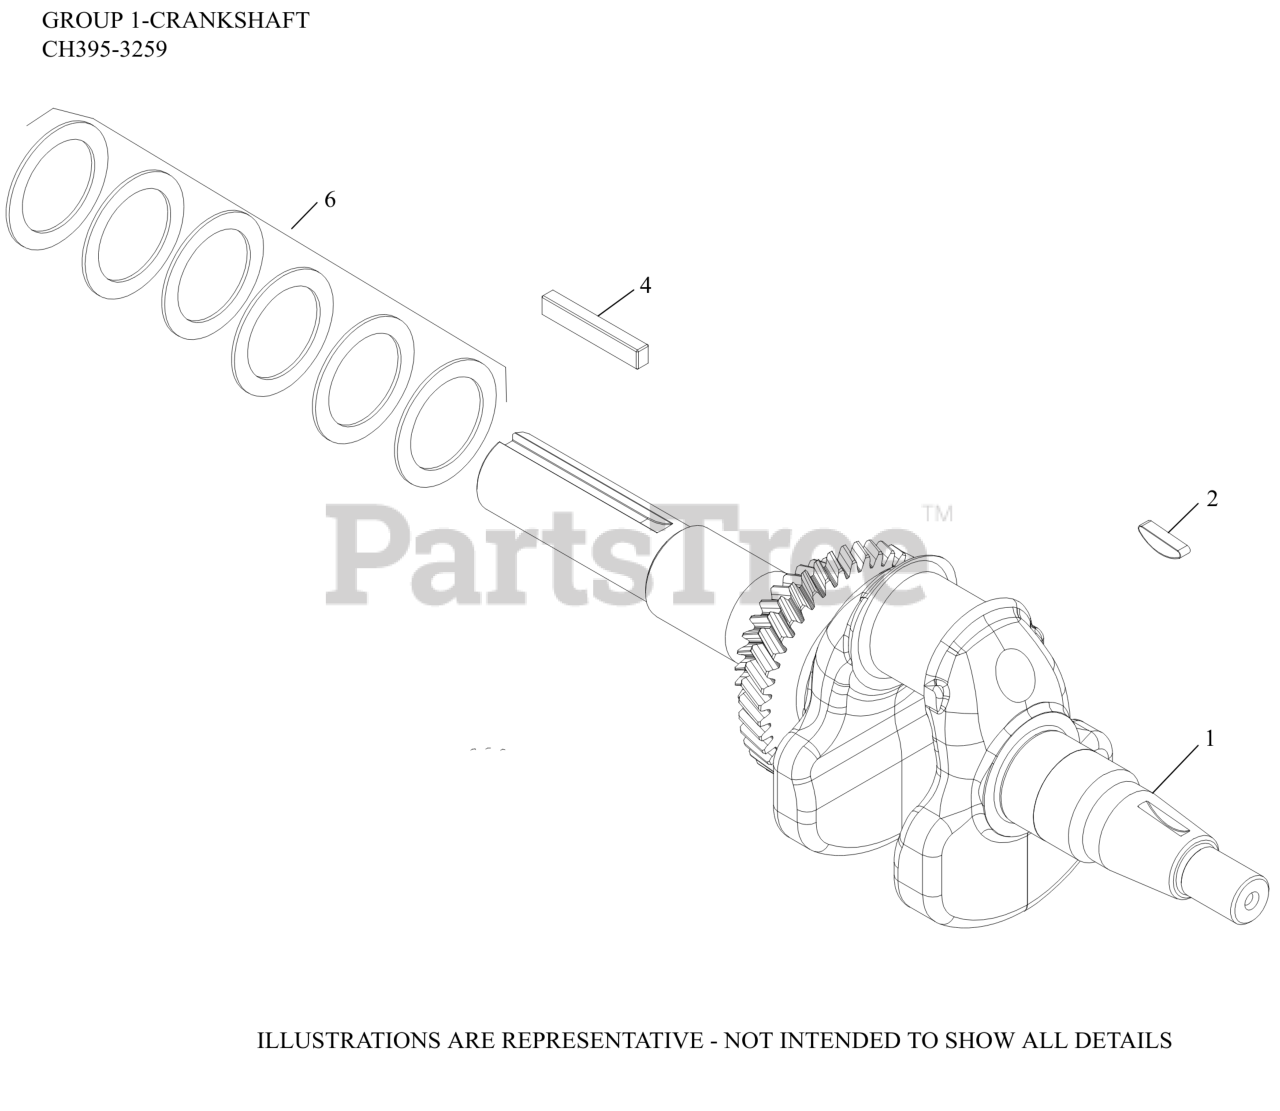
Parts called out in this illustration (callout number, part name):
1	CRANKSHAFT ASSEMBLY
2	KEY, FLYWHEEL
4	KEY, SQUARE
6	KIT, SHIMS
